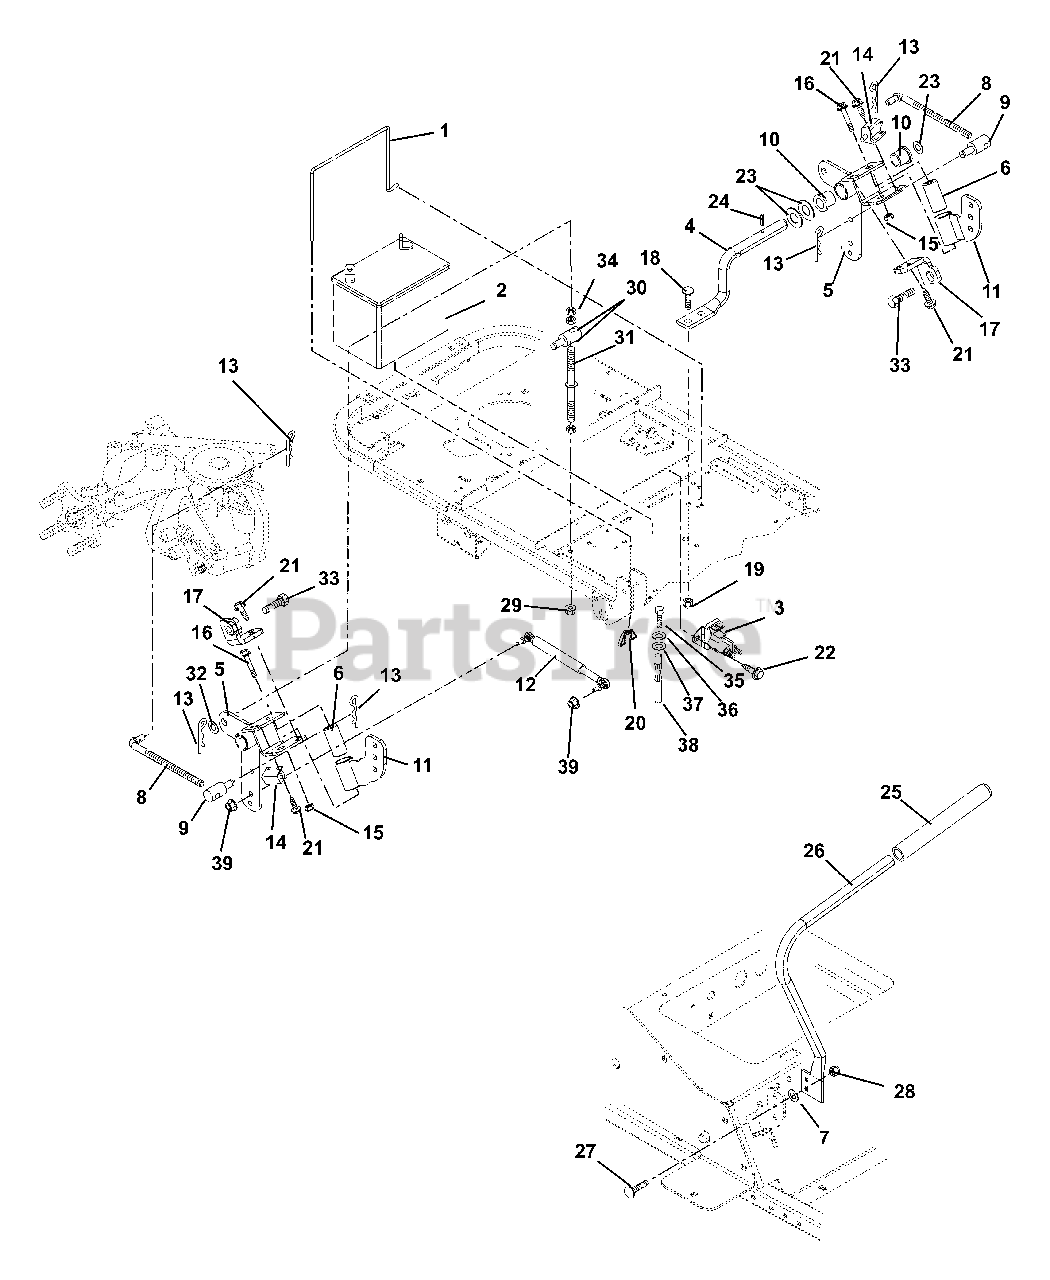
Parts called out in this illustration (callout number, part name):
1	Battery Rod
2	Battery (12 Volt, 330 CCA, 50 Min. Reserve Cap.) (043)
3	Solenoid
4	Rod Pivot
5	Weldment, Control
7	Washer, Locking Extenal .326 x .599 x .031
8	Link, Wireform
9	Pivot, Rod
10	Bushing 1.00 x .75 x 1.00
11	Weldment, Handlebar, RH
11	Weldment, Handlebar, LH
13	Pin, Hair
14	Switch, Double Pole N.O. / N.O.
15	Nut, Locking Top Flange .50-13
16	Bolt, Hex .50-13 x 3.00 Grade 5
17	Bracket, Tracking
18	Bolt, Round Head Square Neck .38-16 x 1.00 Grade 5
19	Nut .38-16 Flange Nyloc
20	Nut, Locking Wing .25-20
21	Screw, Tapping 10-24 x .50 Hex Washer Head
22	Screw, Tapping .25-20 x .37 Hex Washer Head
23	Washer, Flat Steel .754 x 1.00 x .032
24	Pin, Roll .188 x 1.13
25	Grip, Handlebar
26	Handlebar, Right Hand
26	Handlebar, Left Hand
27	Bolt, Round Head Square Neck .31-18 x .88 Grade 5
28	Nut, .31-18 Flange Nyloc
29	Nut, .38-16 Flange Nyloc
30	Nut, Hex .38-16
31	Rod, Tracking
32	Nut, Locking Jam Patch 1.00-20
33	Screw, Socket Head .25-20 x 1.25
34	Trunnion
35	Bolt, Hex .31-18 x 1.00 Grade 5
36	Washer-Locking .31 x .078 Regular
37	Washer-Flat-Steel .344 x .688 x .065
39	Nut, Locking Top Flange 8 x 1.25
